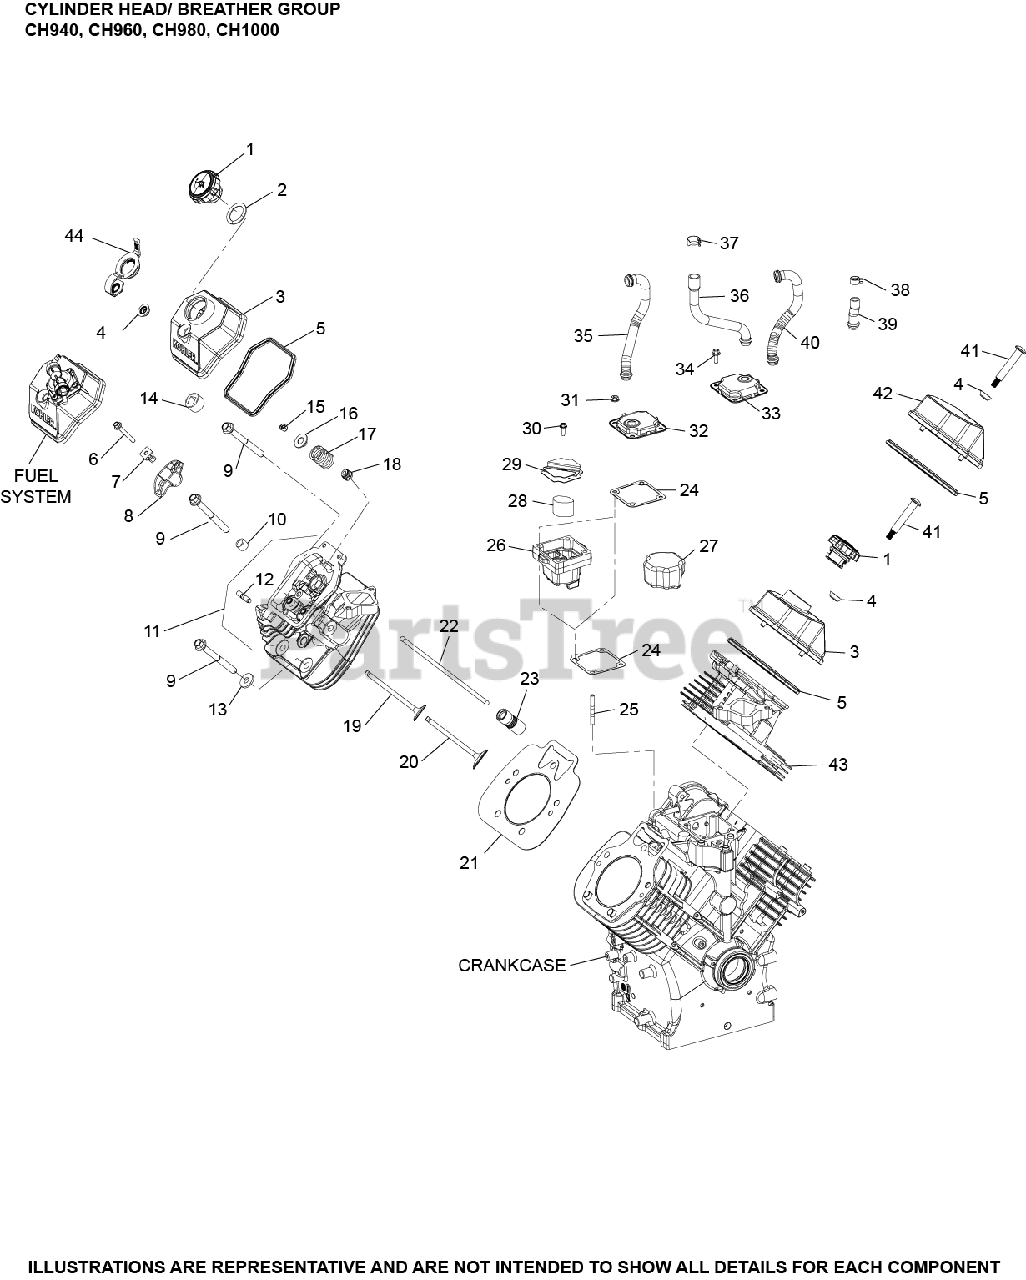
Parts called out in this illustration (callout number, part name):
1	CAP ASSEMBLY
3	KIT, COVER, VALVE (OIL FILL)
4	GROMMET, VALVE COVER SCREW
5	SEAL, VALVE COVER-USE 62 032 20-S
6	SCREW, FLG M6X1.0X45
7	PIVOT, ROCKER ARM
8	ARM, ROCKER
9	SCREW, FLG M10X1.5X90
11	KIT, CYLINDER HEAD #2 - USE 62 318 33-S
13	WASHER, FLAT 13/32"
14	PLUG, PIPE 3/4 NPTF SQ CTSK USE 25 139 89-S
15	KIT, RETAINER
16	CAP, VALVE SPRING
17	SPRING, VALVE
18	SEAL, VALVE BAND
19	VALVE, EXHAUST
20	VALVE, INTAKE
21	KIT, CYLINDER HEAD GASKET
22	ROD, PUSH
23	LIFTER, VALVE HYDRAULIC - (#2535111S)
24	GASKET, BREATHER
27	FILTER, BREATHER USE 62 050 10-S
33	KIT, BREATHER ASSEMBLY
34	SCREW, THREAD FORMING
35	HOSE, BREATHER
36	HOSE, BREATHER
41	SCREW, SHOULDER
43	KIT, CYLINDER HEAD #1 USE 62 318 32-S
